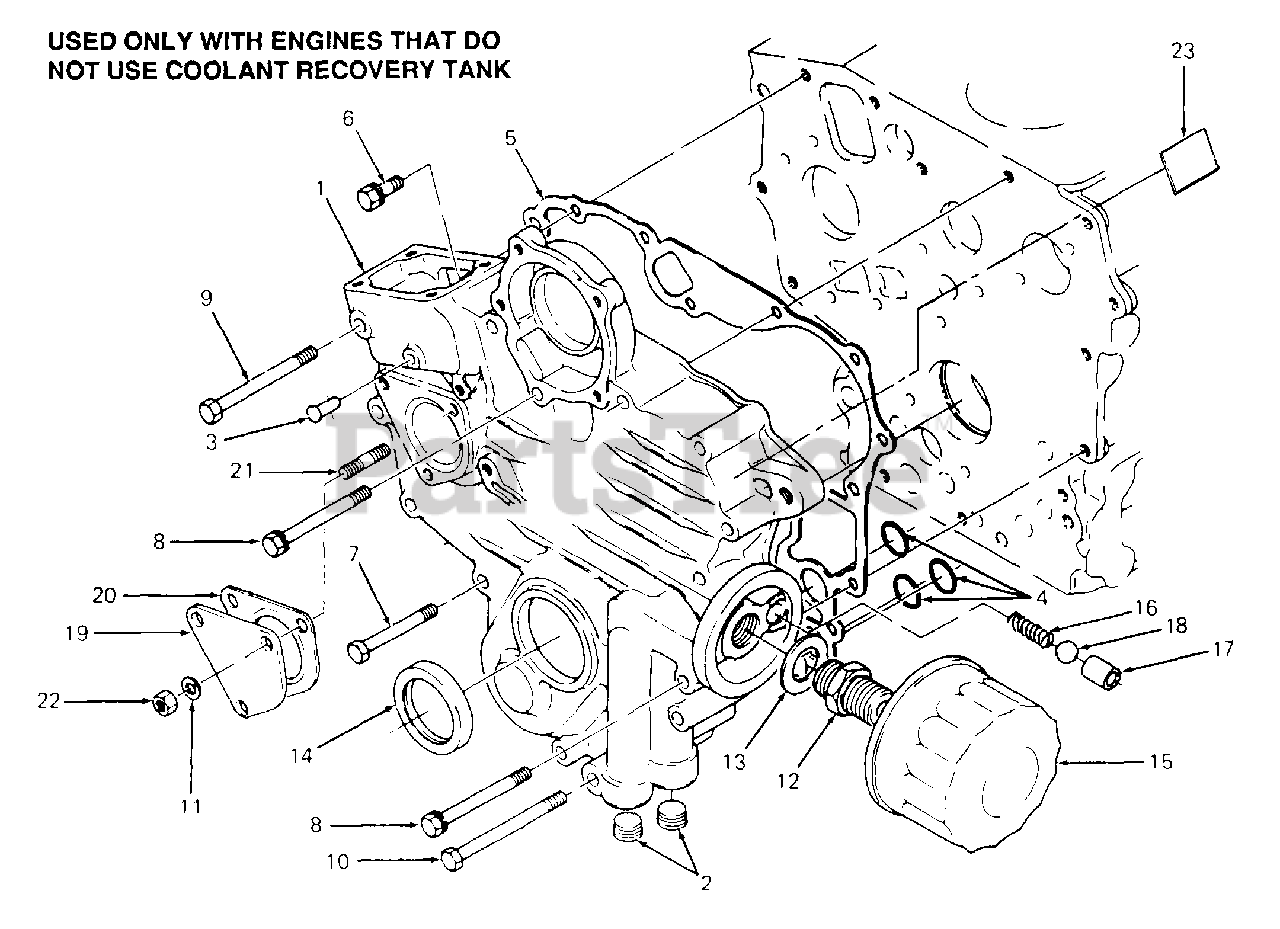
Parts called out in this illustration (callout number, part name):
1	Case Assy, Gear
4	O-Ring, 1/2 X 11/16
5	Gasket, Gear Case
6	Screw, Hex Cap w/Washer
7	Screw, Hex Cap
8	Screw, Hex Cap w/Washer
9	Screw, Hex Cap
10	Screw, Hex Cap
11	Washer, Spring
15	Element, Filter
18	Ball, Metal, 11/32 Dia
